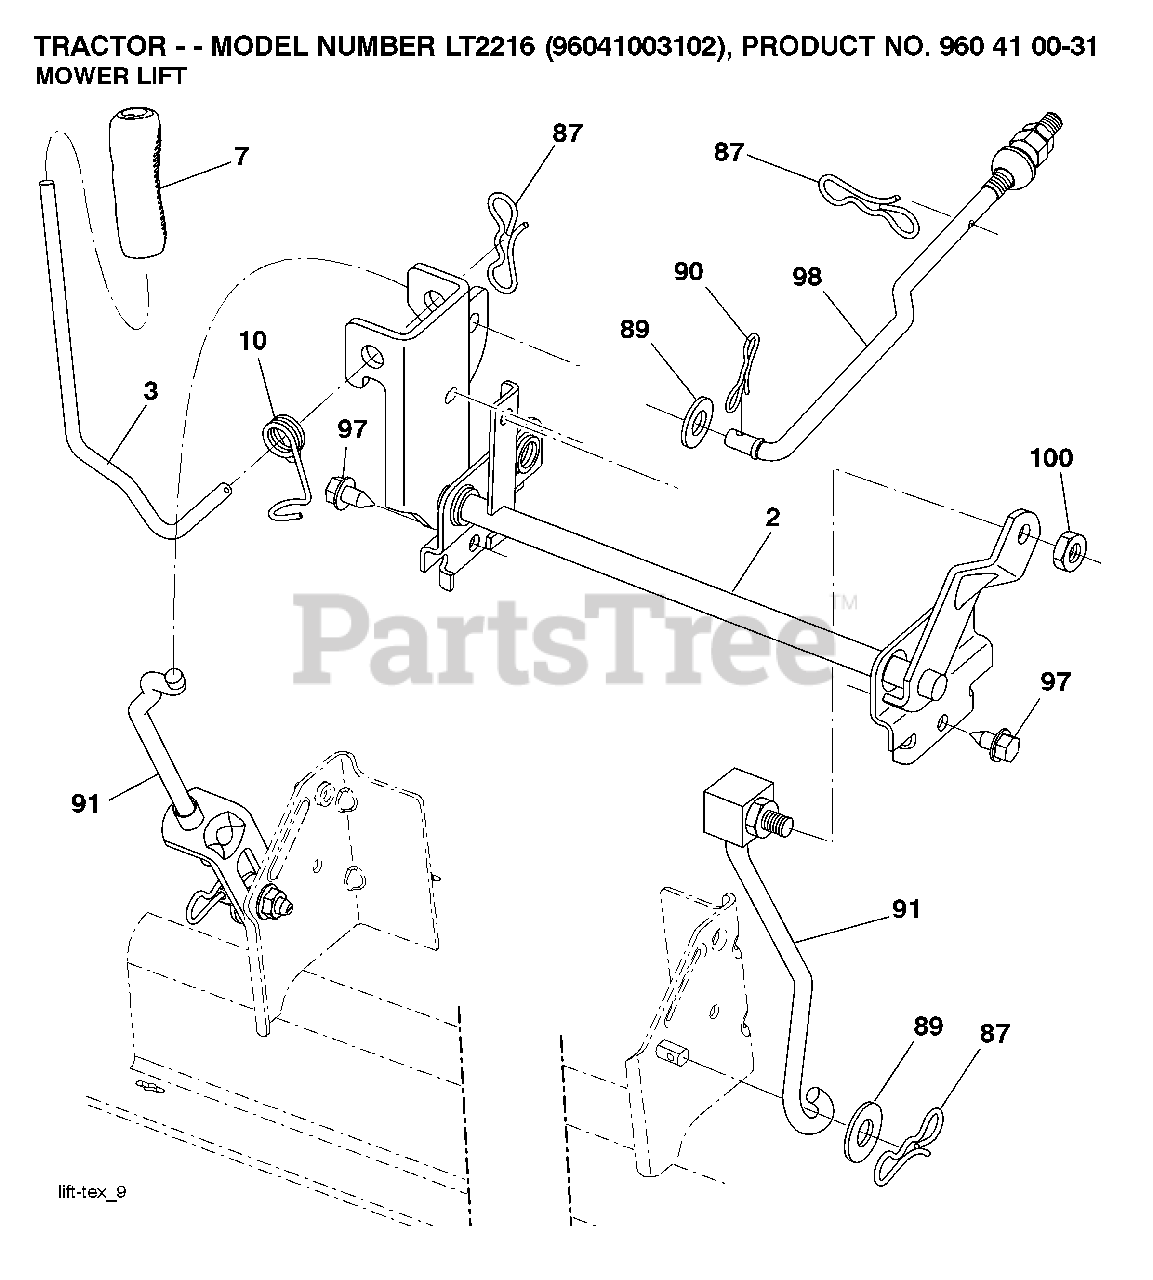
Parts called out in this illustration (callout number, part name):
2	SHAFT.ASM.LIFT.CROSS.H
3	LEVER.LIFT.HANDLE.LT
7	GRIP.LEVER.5625.ID
10	SPRING.TORSION.LIFT.HANDLE
87	PIN.COTTER.7/16.BOW TI
89	WASHER.CLEAR.ZINC
90	PIN.COTTER.5/16.BOW TI
91	LINK.ASM.LIFT.REAR
97	SCREW 3/8-16X3/4
98	LINK.ASM.SUSP.FRONT.MW
100	LOCKNUT
